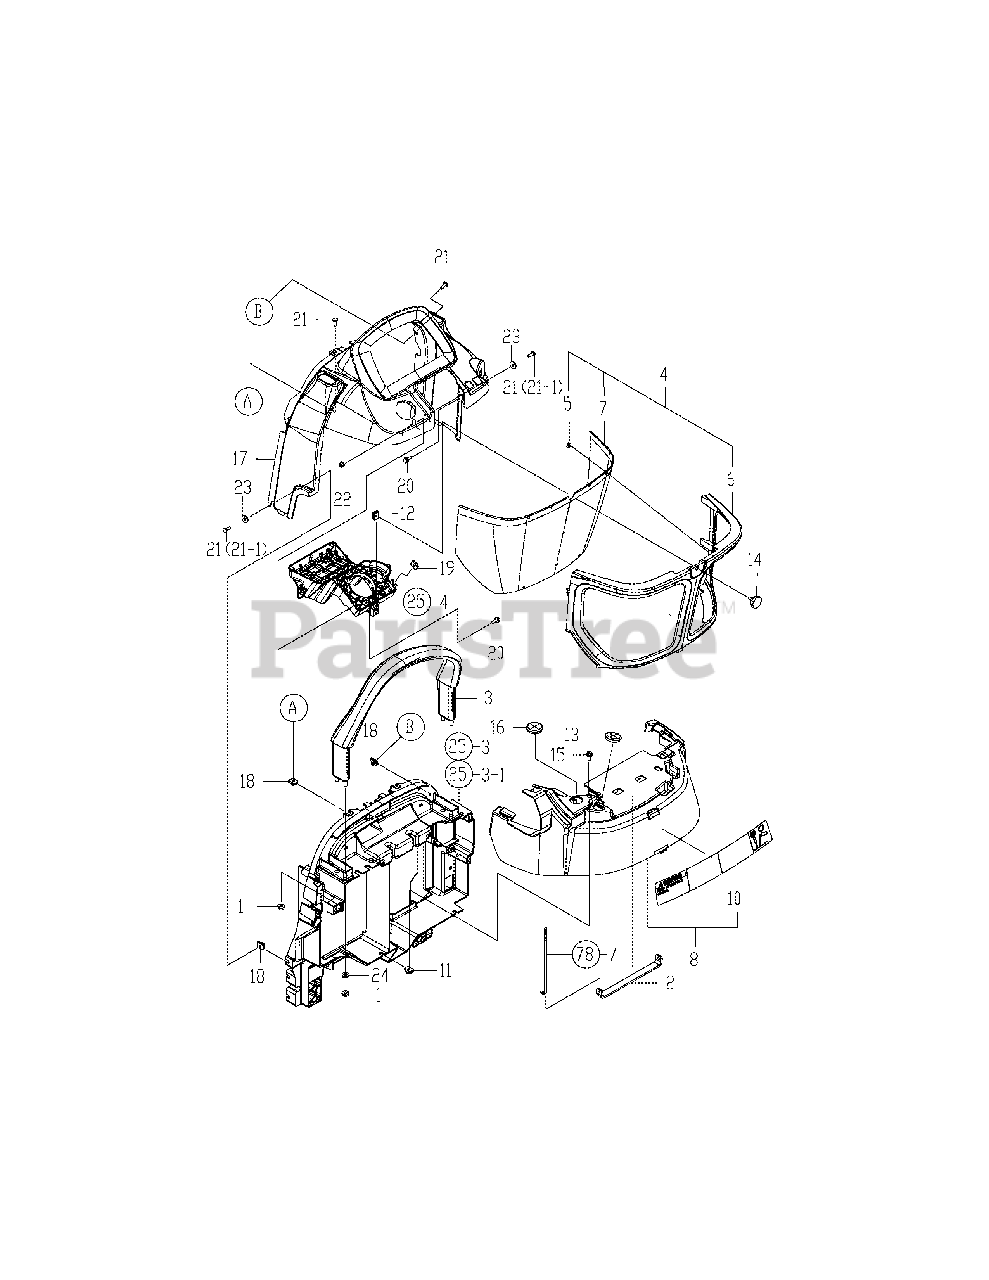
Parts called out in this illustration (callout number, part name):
4	Dushboard Assy, Lwr
6	Cover, Dushboard Lwr
7	Net, Dashcover
8	Cover M Asy, Dash Btm
10	Label, Caution, General
17	Cover, Dashboard Uppr
17-1	Cover, Dashboard Uppr
22	Nut W/Washer 6
